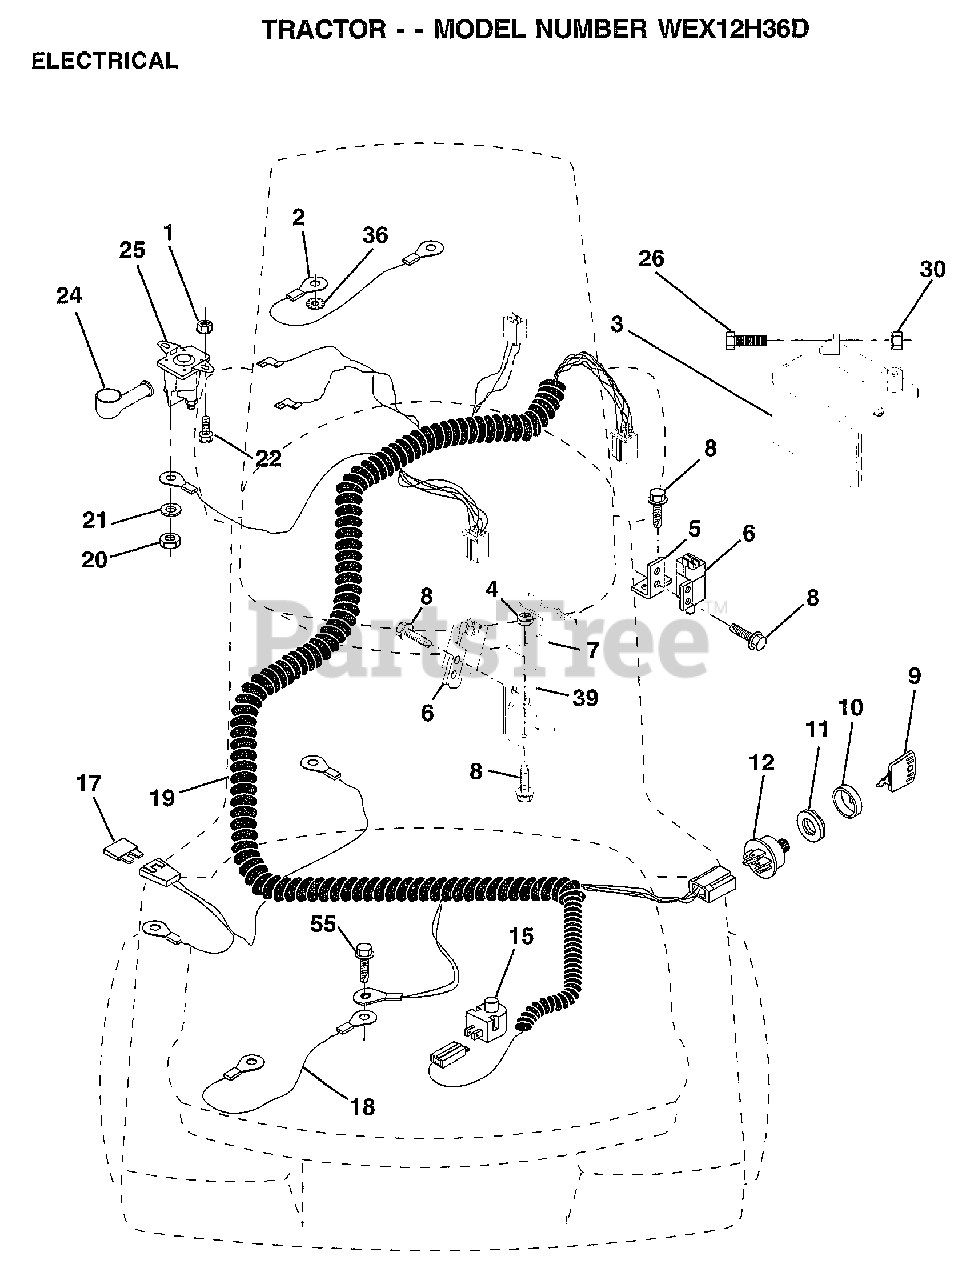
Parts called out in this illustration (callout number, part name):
1	NUT HXKEP 1/4X20
2	CABLE ASM.
4	LOCKNUT
5	BRACKET LT
6	SWITCH INTERLOCKT
7	KEEPER.ACTUAT.LR.
8	SCREW
9	KEY MLD GEN DELTA
10	COVER KEY SWITCH
12	SWITCH.IGNITION
15	SWITCH SEAT
17	FUSE.15 AMP
18	CABLE ASSY
19	HARNESS, IGNITION
20	NUT
22	BOLT HXHD FIN
26	BOLT LT
30	NUT
36	LOCKWASHER
39	BRACKET SWT CLUTC
55	SCREW LT
